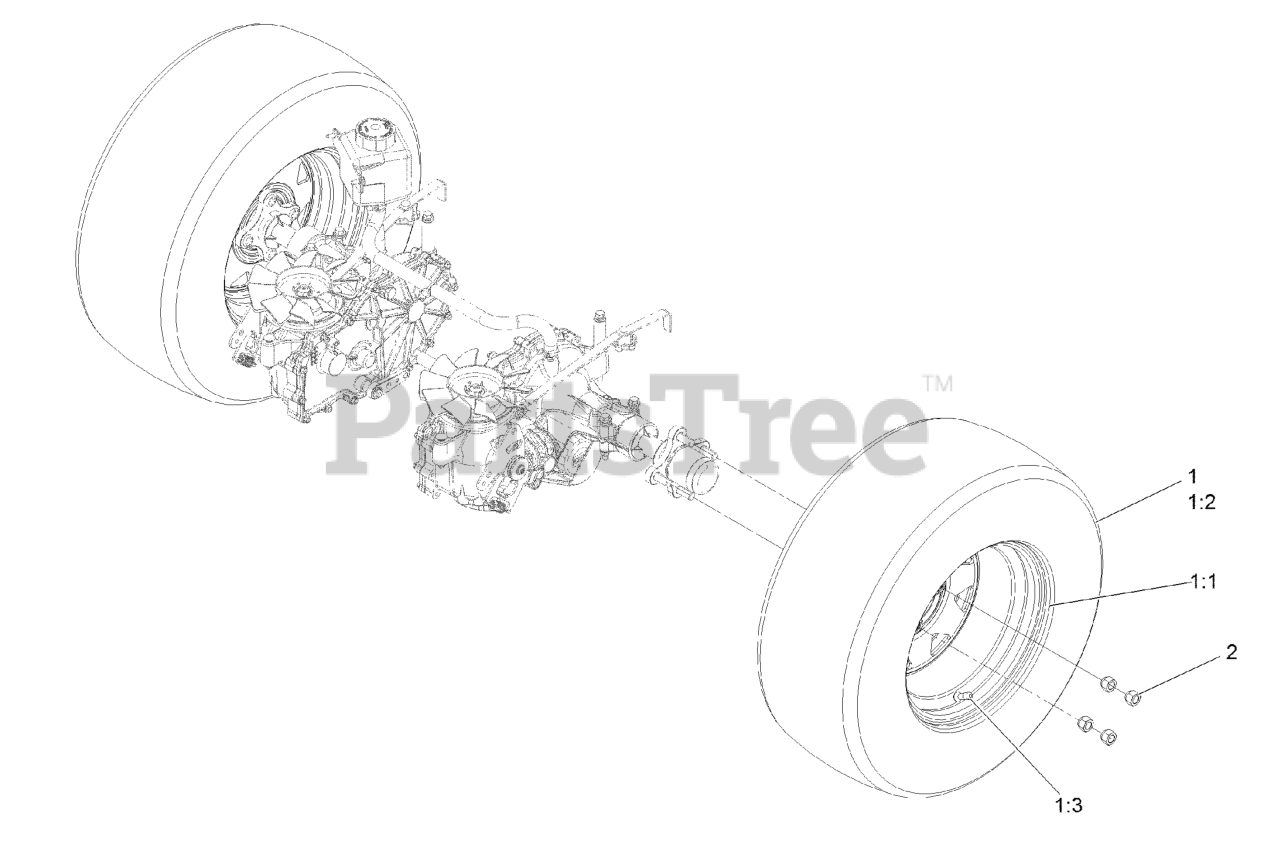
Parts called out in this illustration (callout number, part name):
1	WHEEL AND TIRE ASM
1:1	WHEEL-12X7, 8 SPOKE 4 ON 4
1:3	Stem-Valve
2	NUT-LUG
